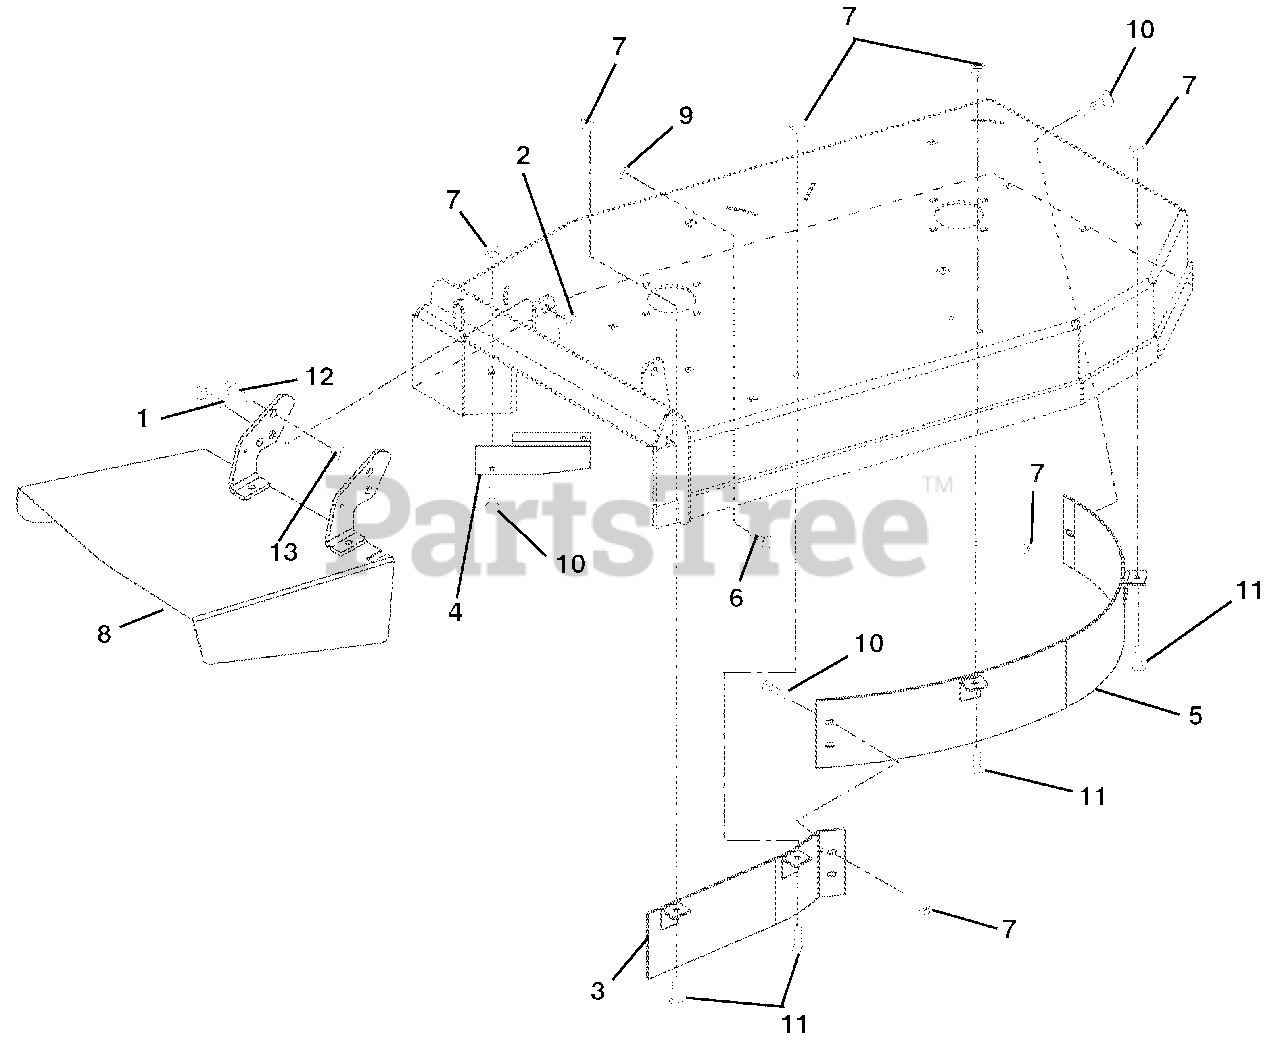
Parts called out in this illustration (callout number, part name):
1	Bolt-Hex .50-13 x 1.25 Grade 5
2	Nut-Locking-Nylon .50-13
3	Weldment- Upper Baffle Right(105, 312)
4	Deflector 36"(105, 312)
5	Weldment- Upper Baffle Left(105, 312)
6	Bolt-Round Head Square Neck .38-16 x 1.00 Grade 5
7	Nut-Locking-Top-Flange .31-18
8	Chute-Discharge
9	Nut-Locking-Top-Flange .38-16
10	Bolt-Round Head Square Neck .31-18 x .75 Grade 5
11	Bolt-Hex .31-18 x .75 Grade 5
12	Bolt-Hex .38-16 x .75 Grade 5 (312)
13	Nut-Locking-Center .38-16 (312)
